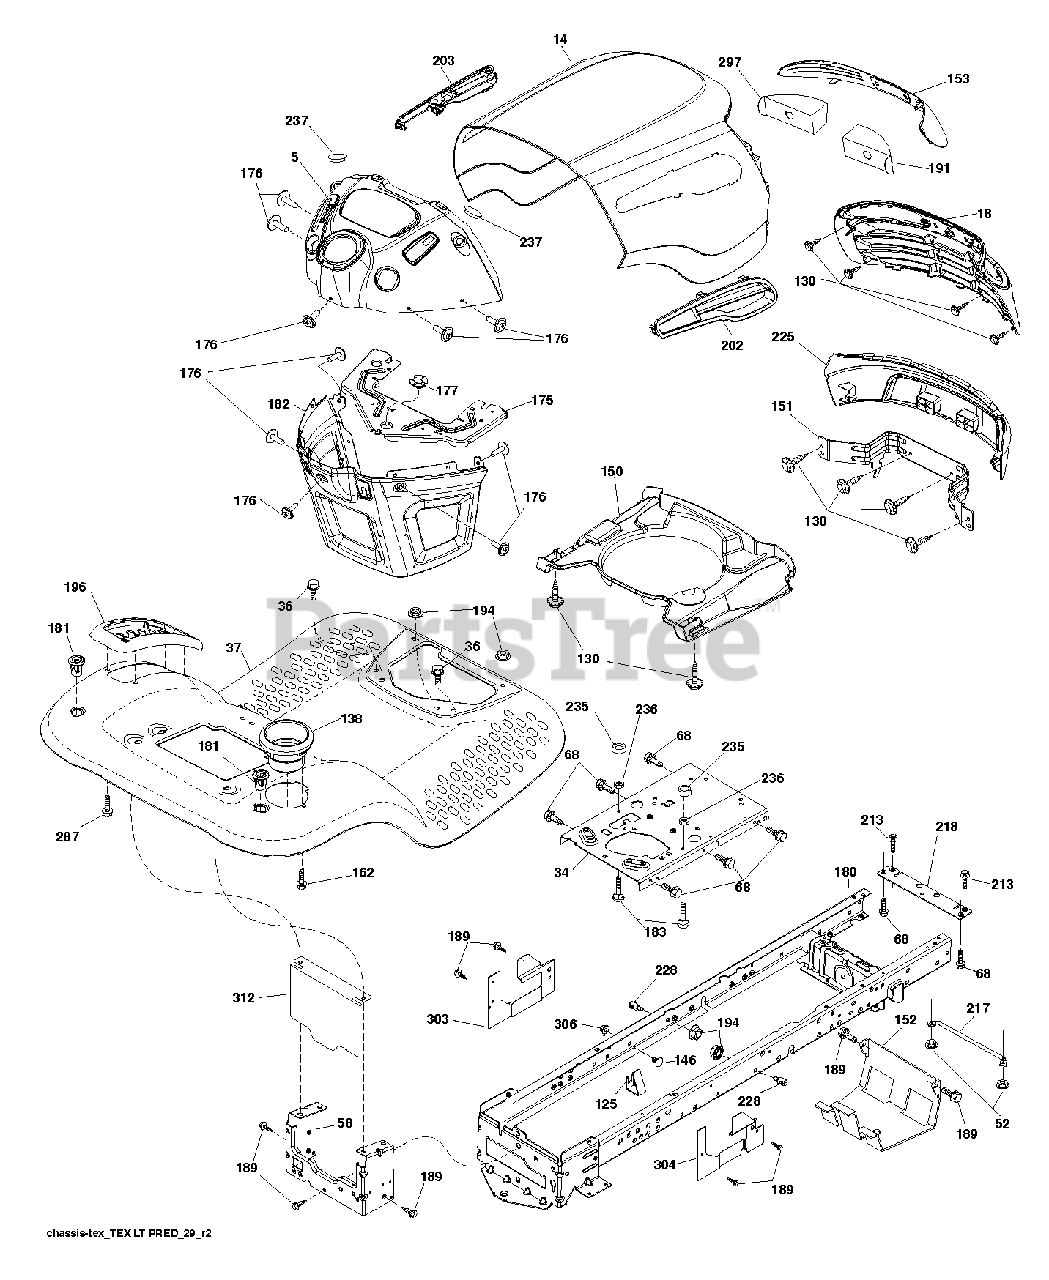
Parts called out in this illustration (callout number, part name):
36	SCREW 5/16"
52	LOCKNUT
58	DRAWBAR UPPER 2PC SMALL FENDER
125	Fuel Line Clip
130	SCREW.#10 X 0.750.BOS THREAD
138	CUPHOLDER.TL.TEX.BLACK
146	BOLT.RDHD.SHT.SQNK.3
151	BRACKET.PIVOT.ALPHA.LT
152	SHIELD BROWNING
153	LENS.PREDATOR.LT
162	SCREW.HI-LO.CONSOLE
175	CROSSMEMBER
176	SCREW.#10-24X5/8.RN.QU
177	BUSHING STEERING
181	FEND/FTRST.PCH.CPH.NFW
182	DASH.LWER.PREDATOR/HUSQ.LT
183	BOLT.5/16-18X1-1/4 FULL THD
189	SCREW
191	INSERT.REFLECT.PREDATOR.LT.RH
194	NUT LOCK HEX FLANGE 5/16-18
196	CONSOLE.ASM.DECKLFT.BL/RBT.TLT
213	BOLT
217	ROD.PIVOT.HOOD
218	X-PIECE.HOOD.STOP.NON/
228	STUD.FASTNER.W/ANTI-ROTATE
235	SPACER FENDER
236	NUT.CENTERLOCK.5/16-
237	PLUG.MOUNT.CARGO.BLK
297	REFLECTOR.INSERT.PRED.LH.LT
306	NUT LOCK FLG 3/8-16 UNC
